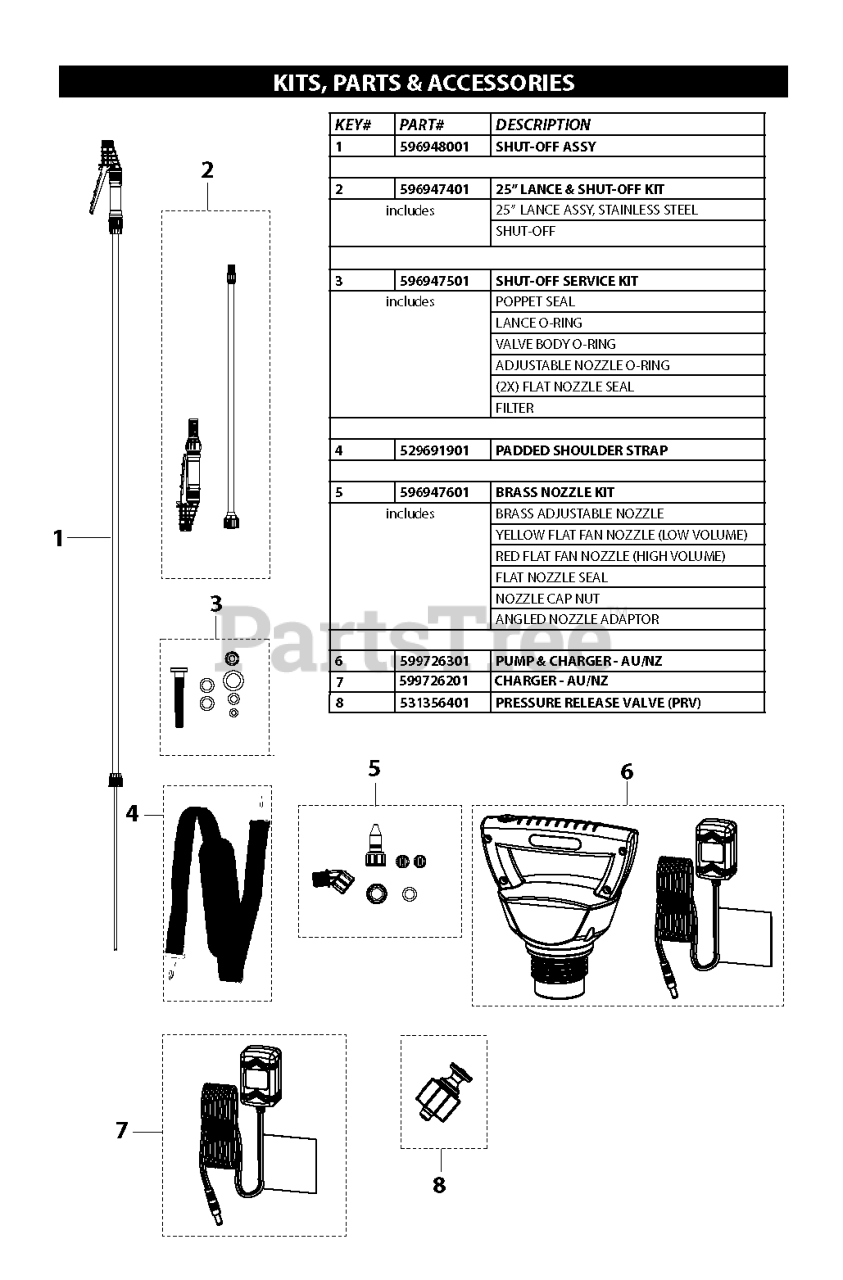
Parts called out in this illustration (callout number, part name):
1	2G SPRAYER SHUTOFF/HOSE ASSY
2	SPRAYER WAND/SHUTOFF KIT
3	SPRAYER SHUTOFF SERVICE KIT
4	Strap
5	SPRAYER NOZZLE KIT
6	SPRAYERS
8	PRESSURE RELEASE VALVE.
